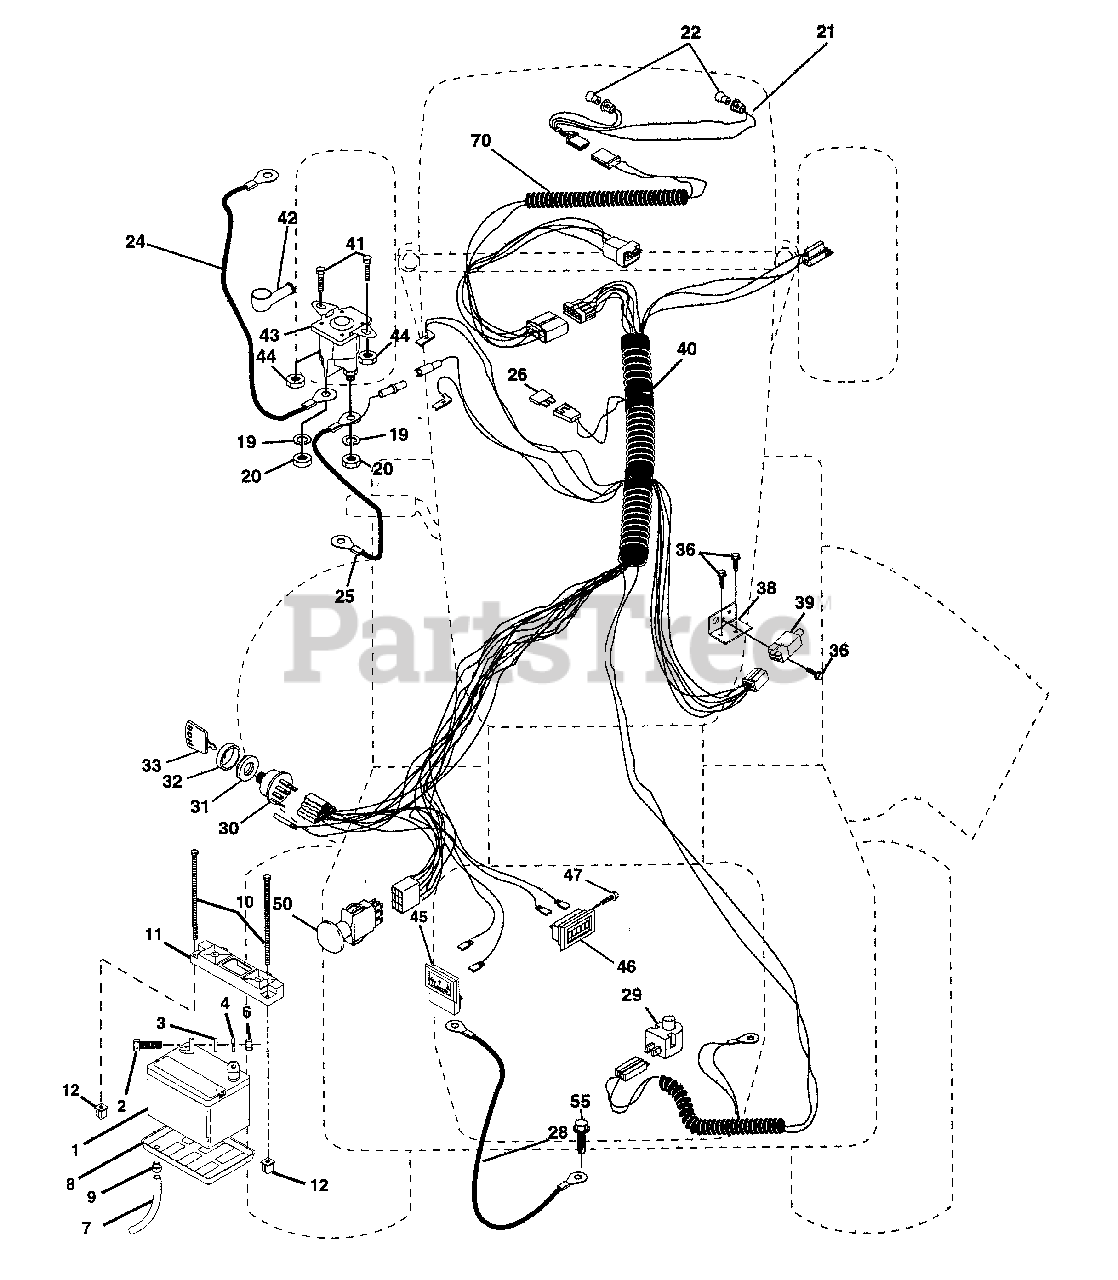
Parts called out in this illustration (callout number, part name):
1	Battery 12 Volt 35 AMP Wet
2	Bolt Hex Hd 1/4-20unc X 3/4
3	Washer 9/32 X 5/8 X 16 Ga.
4	Washer Lock Hvy Helical 1/4
6	Nut Fin Hex 1/4-20 Unc
7	Tube Plastic 46" Front
8	Tray, Battery 7.80 x 5.25 Blk
9	Clamp Hose Olive
10	Bolt BTR FRT 1/4-20 x 7.5 zinc
11	Holddown Battery, Dash mount
12	Nut, Push Nylon 1/4 battery FRT
19	Washer Lock 1/4
20	Nut Jam Hex 1/4-20 Unc
21	Harness Asm Light W/4152j
22	Bulb Light #1156
24	Cable Starter 6 Ga 11" Red
25	Cable Battery 6 Ga 22" w/16W
26	Fuse 30 AMP Auto Green
28	Cable Ground 6 Ga 21" black
29	Switch Plunger Nc Gray
30	Switch Ign 4 pos w/lights
31	Nut Ignition
32	Cover Sw Ignition
33	Key Ign Modleded Generic
36	Screw Tap Hex #10-24unc X 1 /2
38	Bracket, Switch, Interlock
39	Switch Intlk Clutch Grey 4 Term
40	Harness Ign. Elec. HM P/L
41	Bolt Blk Fin Hex 1/4 - 20 x 1/2
42	Cover Terminal Red
43	Solenoid
44	Nut Keps Hex 1/4-20 Unc
45	Ammeter, retangular 15 amp
46	Meter, Hour
47	Screw 10-24 x 1/2 Black
50	Switch PTO 3 PTD Black
55	Screw THDROL 5/16-18 x 1/2 TYT
70	Harness, Eng.
